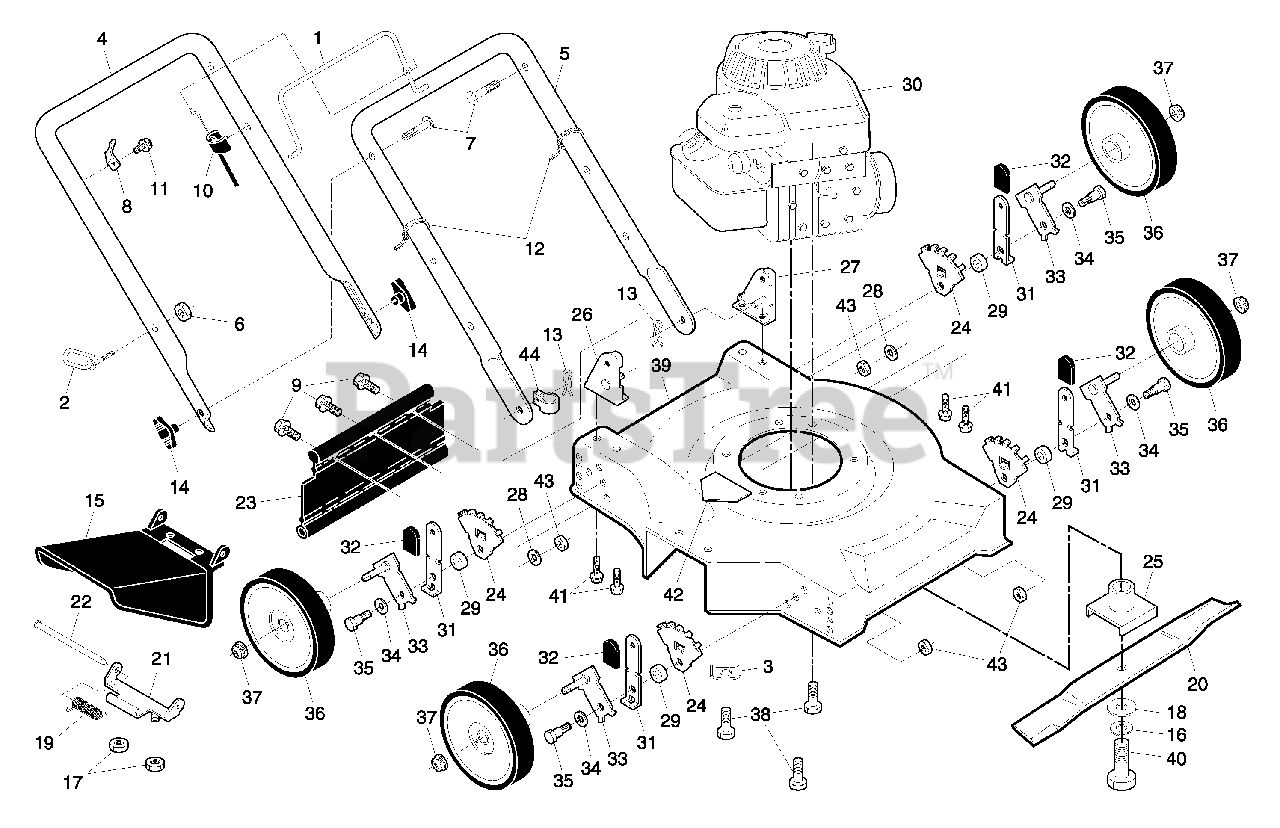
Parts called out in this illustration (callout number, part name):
1	Control Bar
2	Rope Guide
3	Washer, Engine, Zinc Plated
4	Upper Handle
5	Lower Handle
6	Nut, Hex 1/4-20
7	Bolt, Handle 5/16-18 x 1-3/4
8	Up-Stop Bracket
9	Screw, Hex Washer Head #10-24 x 1/2
10	Cable, Operator Presence
11	Screw
12	Wire Tie
13	Hairpin Cotter
14	Knob, Handle
15	Discharge Guard
16	Washer, Lock, Helical Spring 3/8
17	Locknut, Hex 1/4-20
18	Washer, Hardened
19	Spring, Torsion
20	Blade, 20"
21	Hinge Bracket
22	Hinge Rod
23	Rear Skirt
24	Bracket, Wheel Height Adjustment
25	Blade Adapter
26	Handle Bracket Assembly, RH
27	Handle Bracket Assembly, LH
29	Spacer
31	Selector Spring
32	Selector Knob
33	Axle Arm Assembly
34	Washer, Belleville
35	Bolt, Shoulder
36	Wheel & Tire Assembly
37	Nut, Hex
38	Screw, Hex Head, Threaded, Rolled 3/8-16 x 3/4
39	Housing Assembly
40	Screw, Hex Head, Grade 8, 3/8-24 x 1-3/8
41	Screw, Thread Cutting 5/16-18 x 3/4
42	Decal, Danger
43	Locknut, Hex 3/8-16
44	Clip, Cable
